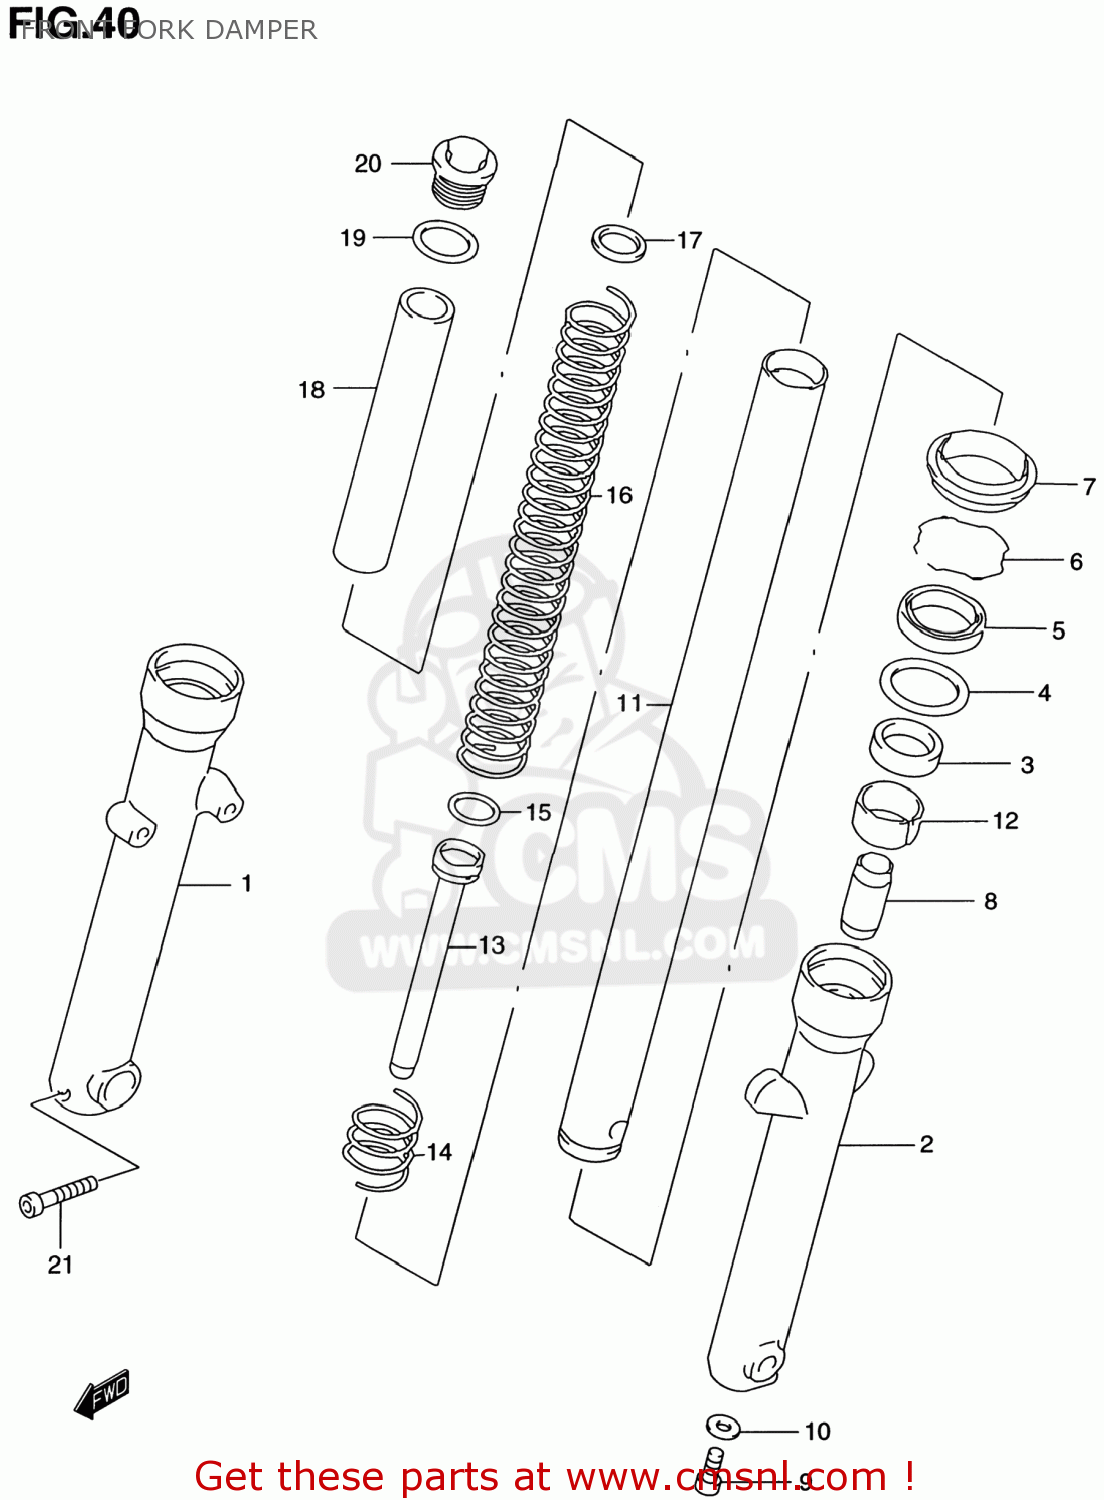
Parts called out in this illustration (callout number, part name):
1	TUBE,OUTER,R
2	TUBE,OUTER,L
3	BUSHING,GUIDE
4	SPACER,SEAL
5	OIL SEAL,FRONT FORK
6	RING,STOPPER
7	SEAL,DUST
8	PIECE,OIL LOCK
9	BOLT,CENTER (8X18)
10	GASKET (NAS)
11	TUBE,INNER
12	BUSHING,SLIDE
13	PIPE,SEAT
14	SPRING,REBOUND
15	RING,PISTON
16	SPRING,FR
17	JOINT,SPRING
18	SPACER,SPRING
19	O RING
20	BOLT,FR FORK
21	BOLT
